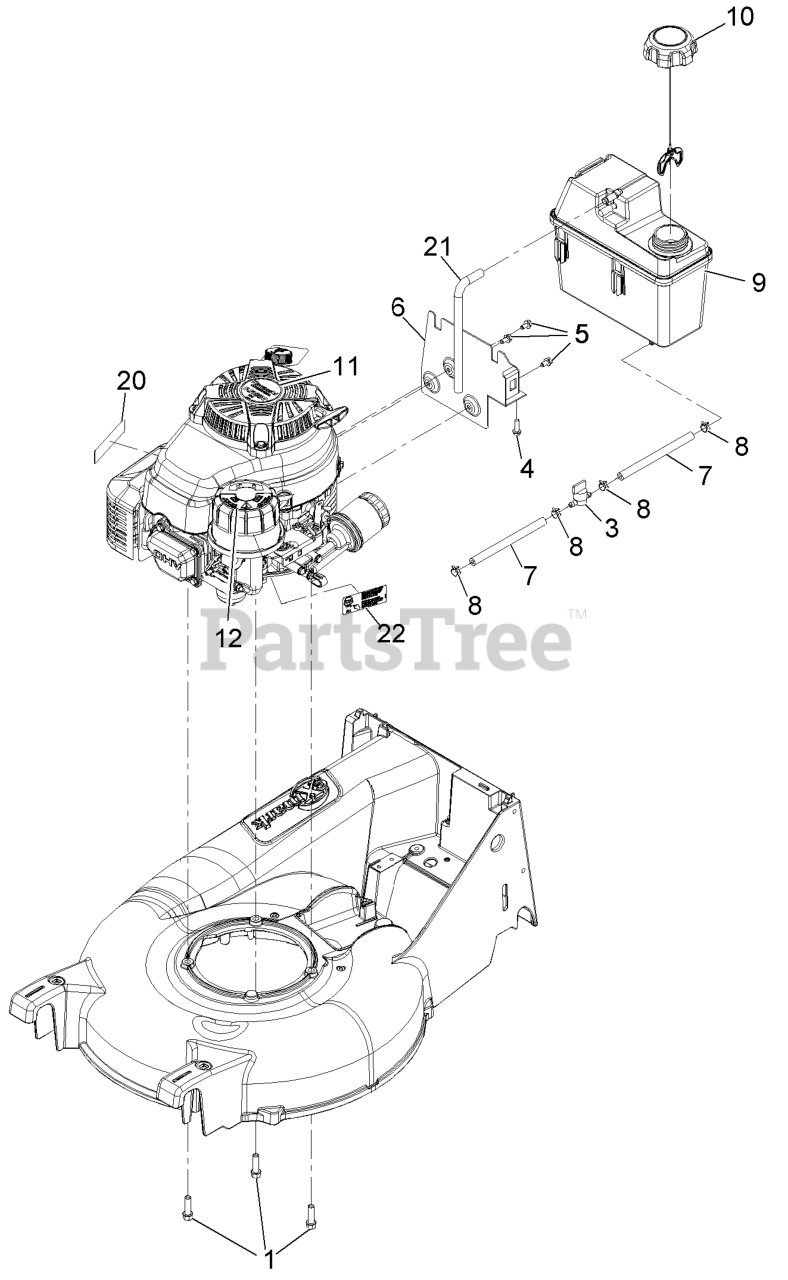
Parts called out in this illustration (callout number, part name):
1	SCREW-TAPTITE
3	VALVE-FUEL
4	SCREW-HWH
5	SCREW-HWH
6	BRACKET,FUEL TANK
7	HOSE-FUEL
8	CLAMP-HOSE
9	TANK-FUEL
20	DECAL-ARRESTER, SPARK
21	HOSE-VENT, CANISTER
22	DECAL, PRIMER
